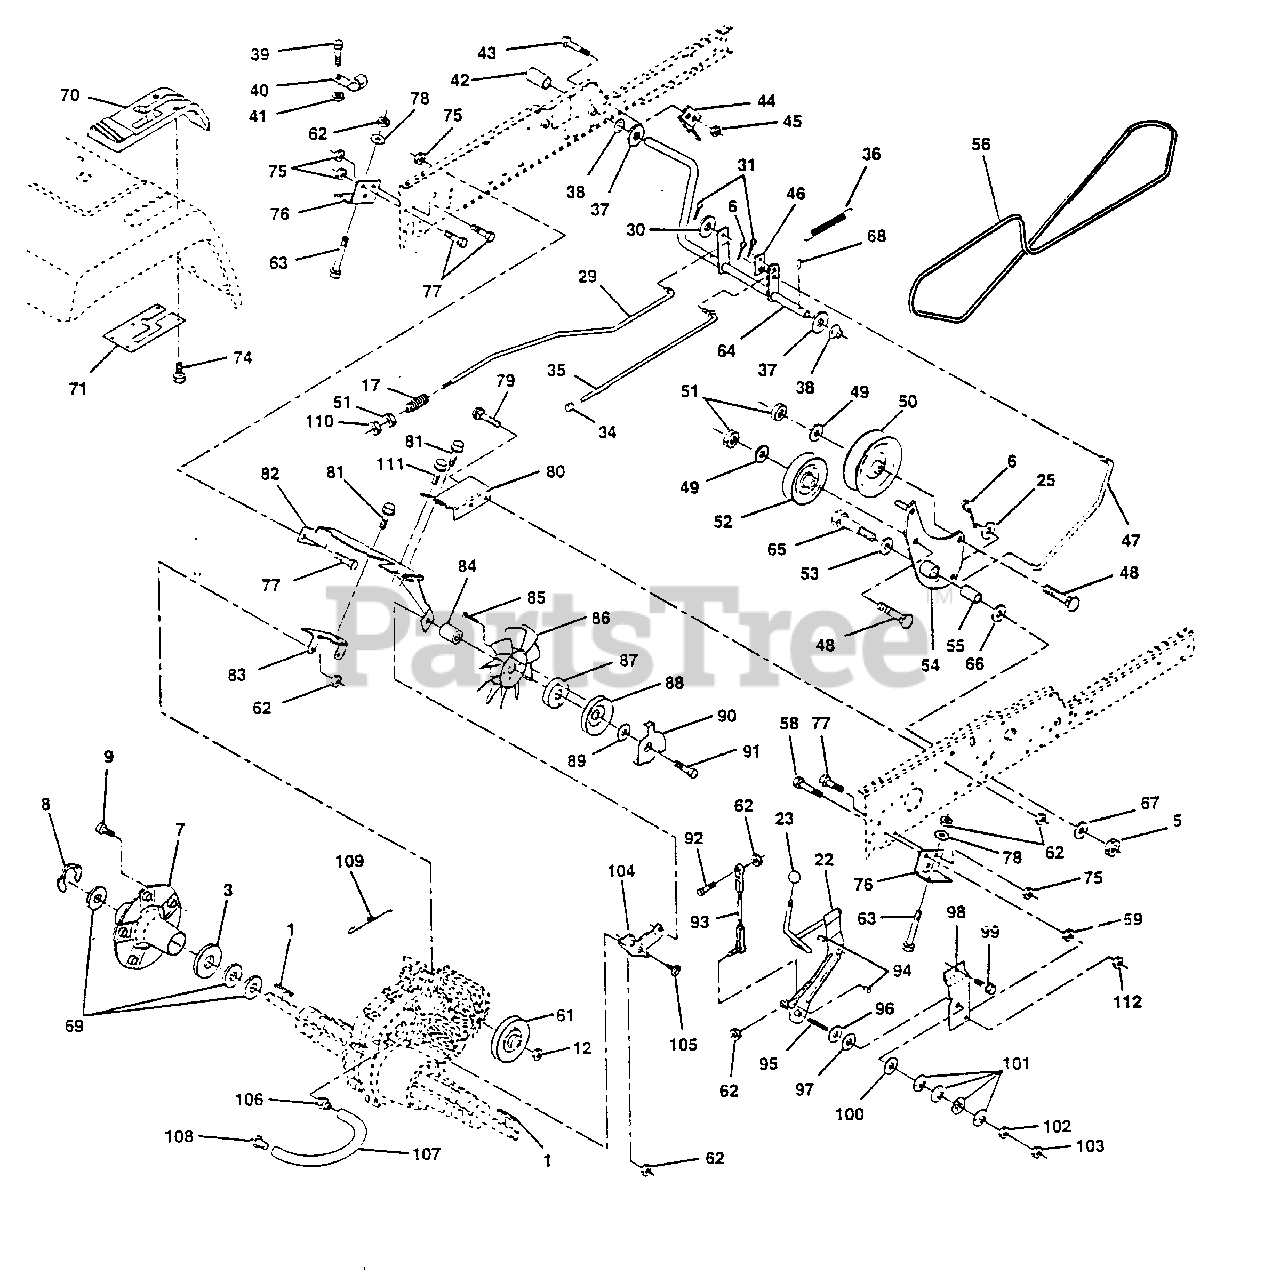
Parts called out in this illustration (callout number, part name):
1	Key 1/4 x 2.5
3	Washer Thrust Axle Harden
5	Nut Crownlock 3/8-16
6	Pin Cotter 1/8 x 3/4
7	Wheel Hub Asm.
12	Nut Hex Jam Toplock 1/2-20
17	Spring Rod Brake
22	Shaft Arm Asm
25	Washer 13/32 x 13/16 x 16 Ga.
30	Washer 13/32 x 1 x 14Ga
31	Pin Cotter 3/32 x 3/4
35	Rod Parking Brake
36	Spring Extension
37	Washer 25/32 x 1-1/4 x 16 Ga.
38	Nyliner
39	Screw Fin #10-24 x 1
40	Actuator Interlock Switch
41	Nut Lock #10-24
43	Bolt Hex Head 1/4-20 x 3/4
44	Bracket Interlock
45	Nut Lock W/Insert 1/4-20
46	Retainer Spring
48	Bolt Carriage 3/8-16 x 1-3/4 Gr. 5
49	Washer 13/32 x 7/8 x 13 Ga
50	Pulley Idler Flat
51	Nut Lock Hex 3/8-16
52	Pulley Idler Grooved
53	Washer Hartdened
54	Clutch Arm Asm
55	Bearing, Idler
58	Bolt Fin Hex 7/16-14 x 1-1/2
59	Nut Hex 7/16-14
61	Pullery Transaxle
62	Locknut Hex W/Washer Insert
63	Bolt Fin Hex 5/16-18 x 3
64	Shaft Asm Brake Parking Clutch
65	Bolt Shoulder
66	Washer Hardened
67	Washer 13/32 x 13/16 x 12 Ga
70	Console Hydro Fender
71	Plate Console Shift
74	Screw, Hex Wsh Hi-Lo 1/4-1/2
75	Nut Lock Hex 7/16
76	Bracket Transaxle
77	Bolt Fin Hex 7/16-14 x 1
78	Washer 11/32 x 3/4 x 12 Ga.
79	Bolt Carriage 5/16-18 x 5/8
80	Bracket Torque RH
81	Screw Thdrol 3/8-16 x 3/4
82	Bracket Mount Torque/Fan
83	Strap Torque Mid
85	Screw #10-24 x 1-1/4
88	Pulley Idler
89	Washer 13/32 x 13/16 x 12 Ga.
91	Screw Thdrol 3/8-16 x 2-3/4
92	Bolt Fin Hex 5/16-18 x 1.75
93	Link Shift Asm
94	Fastner Christmas Tree
95	Screw Set 5/16-18 x 1.75
96	Washer Nickel Plated
97	Bearing Trust
98	Bracket Shift
99	Screw Thdrol 3/8-16 x 1-1/2
100	Washer Compression
101	Washer Bellville
102	Nut Hex Nylok
103	Nut Hex Jam 5/16-18
104	Bracket Idler
105	Screw Tap 1/4-20 x 1/2
106	Fitting Vent Hose
109	Spring Return Brake
110	Nut, Hex Jam 3/8-16
112	Nut, Crownlock 7/16-14
